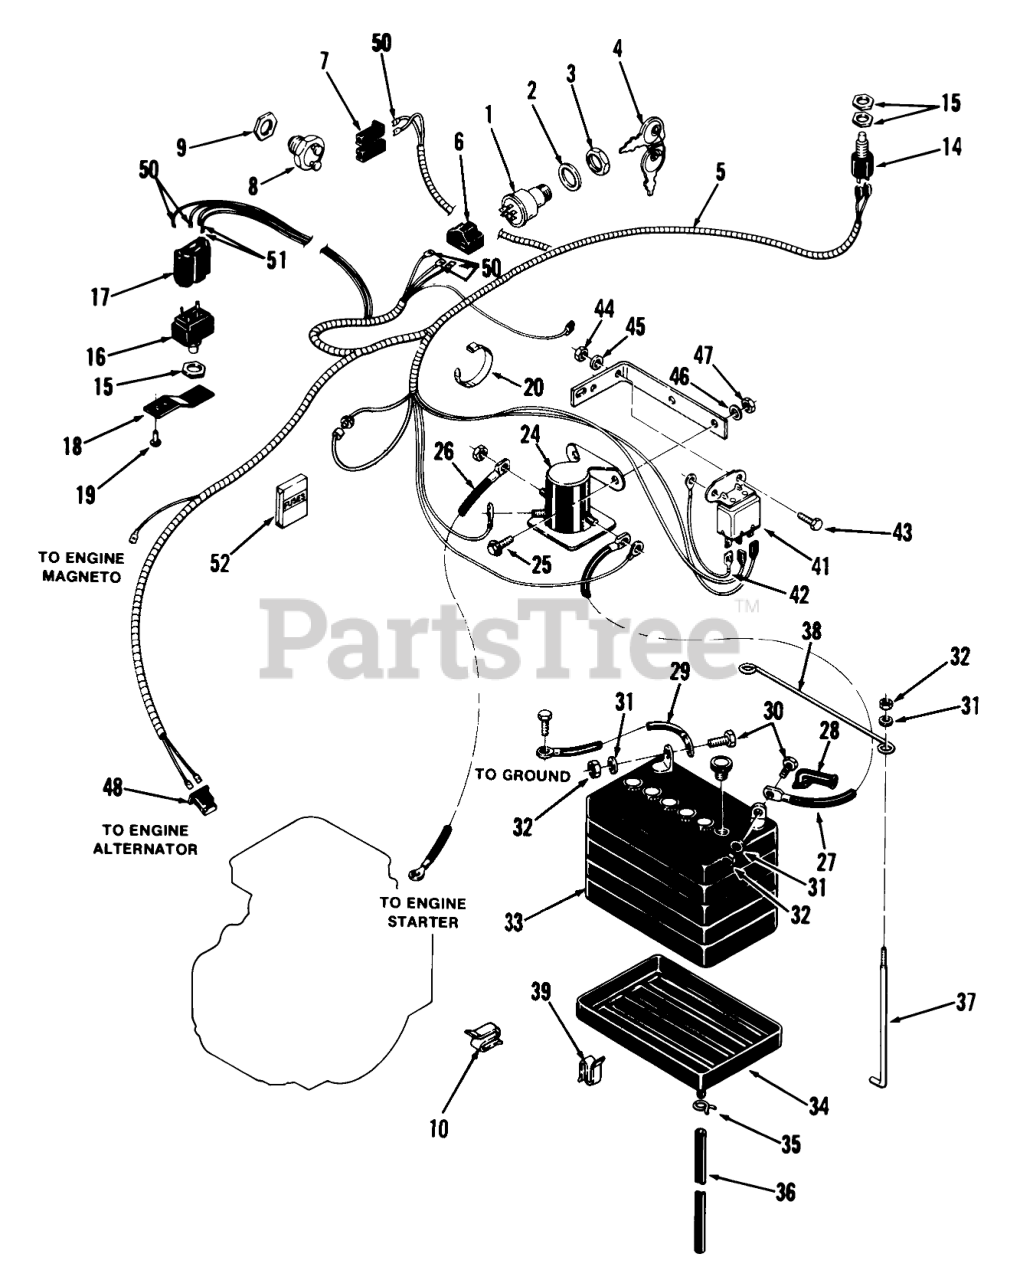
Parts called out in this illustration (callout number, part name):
1	SWITCH-IGNITION
2	LOCKWASHER
4	Key-EL
5	Wiring Harness
6	CONNECTOR-5 WAY-SERV
7	Connector Housing Pedal Switch
8	SWITCH-INTERLOK CLUT
9	NUT-SPECIAL 9/16-18
10	SPEED CLIP
14	SWITCH
15	NUT-HEX
16	SWITCH-CLUTCH
17	CONNECTOR 5 WAY
18	CLIP-SWITCH
19	RIVET
20	PLASTIC TIE
24	SOLENOID
25	Screw
26	Wire
27	Cable
28	Terminal Cover
29	WIRE-GROUND
30	Bolt
32	Nut
33	Battery
34	TRAY-BATTERY
35	Clamp
36	FUEL HOSE 13" OF 6554
37	Hook
38	ROD-HOLD DOWN
39	CLIP
41	Relay
42	RELAY-GROUND WIRE
43	Bolt 10-32 X 5/8
44	Nut
45	Lockwasher Internal
46	LOCKWASHER
47	Nut
48	Conn Body Part of 7
50	Terminal
51	TERMINAL-TAB RCPT
